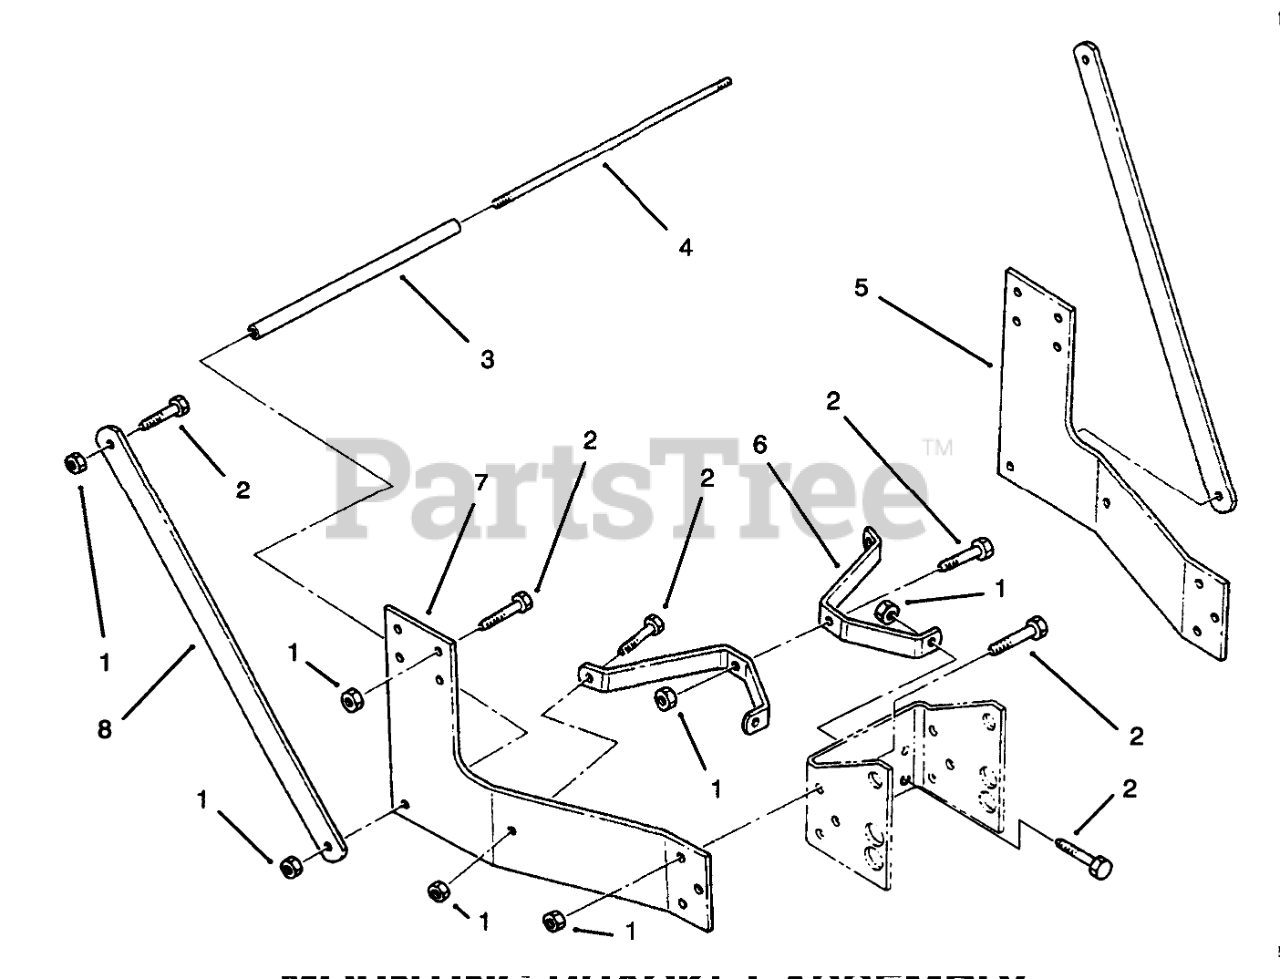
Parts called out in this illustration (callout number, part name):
1	NUT-LOCK, NI
2	SCREW-HH
3	SUPPORT TUBE
4	SUPPORT ROD
5	Bracket-LH.
6	Brace-Center
7	Bracket R.H.
8	Brace
